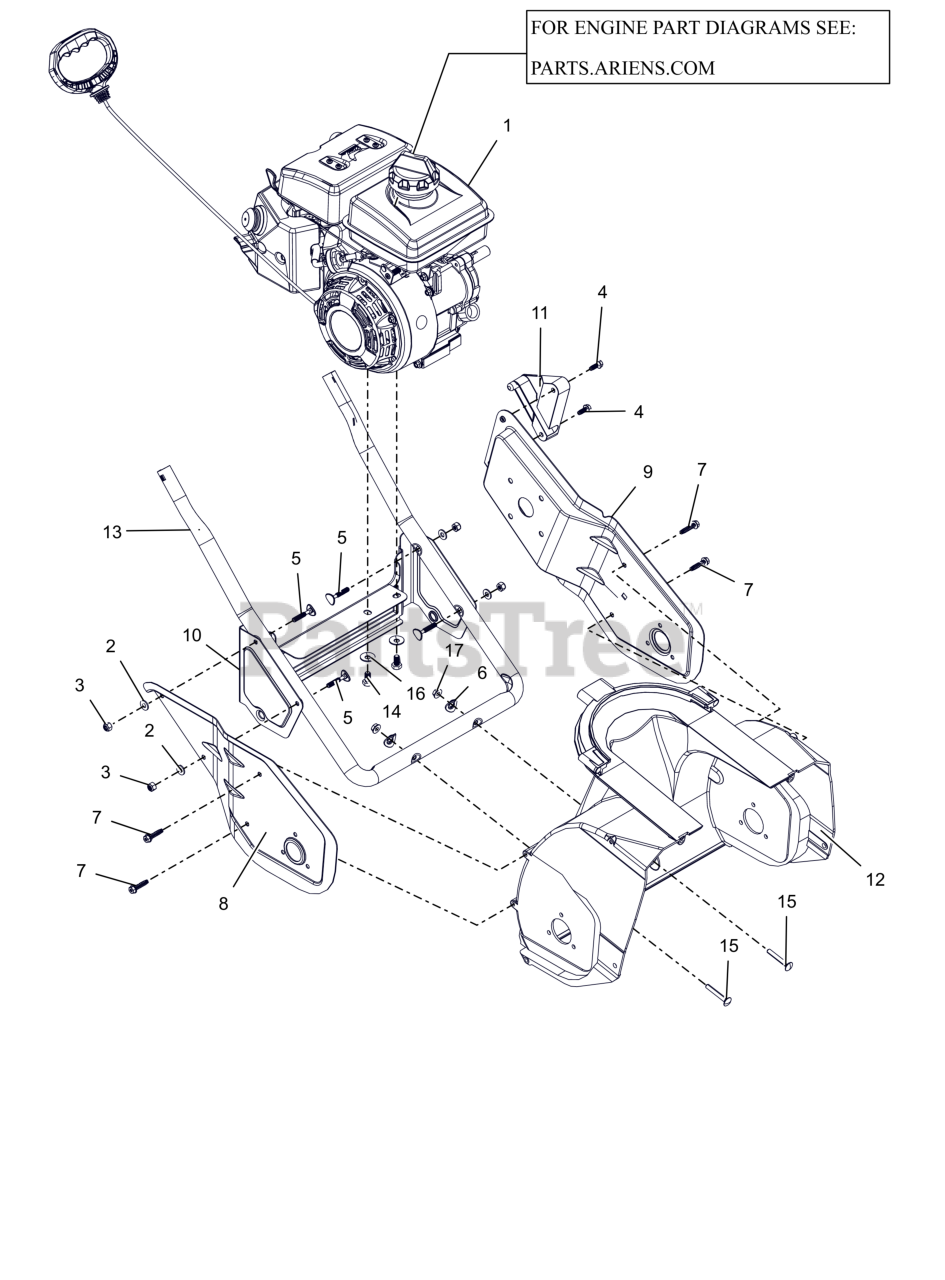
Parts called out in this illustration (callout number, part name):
1	ENGINE, LONCIN 99 PULL START
2	WSHR,FLT .281X.625X.065 ZCC
3	NUT, NYLON .250 - 20 (BLACK)
4	1/4-20 X 5/8 TAPTITE
5	HANDLEBAR, SCR - 1/4-20 - 1"DIA
6	WSHR, HANDLEBAR - 5/16
7	1/4"-10x1.12 TRI-LOBE SCREW
8	PLATE, SIDE - RH
9	PLATE, SIDE - LH
10	WHEEL, BRKT
11	BRKT, FENDER SUPPORT
12	HOUSING, LOWER
13	LOWER, HANDLEBAR
14	SCR, CAP - M8X1.25 H6 THREAD
15	BLT, RDHDSQSHK .25-20X1.75 (BLACK)
16	WSHR, BEVEL SPRING LOCK
17	NUT-LK-CTR-FLG .25-20 ZC120
